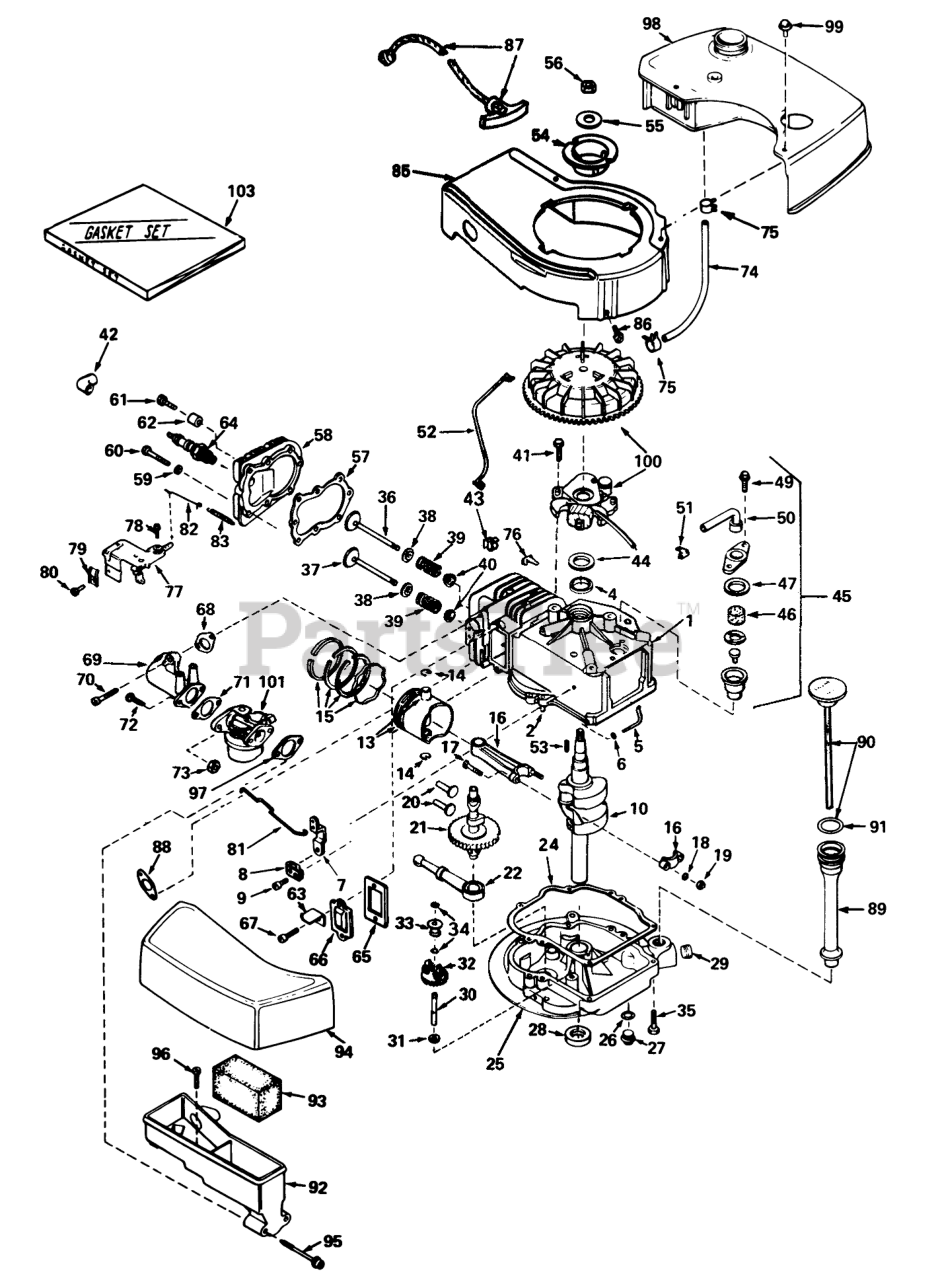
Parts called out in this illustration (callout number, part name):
1	Cylinder assembly (Incl. Ref. #2, 4 & 87)
2	Pin, Dowel
4	OIL SEAL
5	Rod, Governor (Incl. Ref. #6
6	Washer-Flat
7	Governor Lever
8	Clamp-Lever, Governor
9	Screw, Hex Slotted Washer Hd.
10	Crankshaft
13	Piston & Pin Assembly (Incl. 2 of No. 14)(Std.)
13	Piston & Pin Assembly (Incl. 2 of No. 14)(.010 Oversize)
13	Piston & Pin Assembly (Incl. 2 of No. 14)(.020 Oversize)
14	Ring-Retaining, Piston Pin
15	Ring Set Piston (Std.)
15	Ring Set Piston (.010 Oversize)
15	Ring Set Piston (.020 Oversize)
16	Rod Assembly, Connecting (Incl. Ref. #17, 18 & 19)
17	Bolt, Connecting
19	LOCKNUT
20	Lifter-Valve
21	Camshaft(Mech.Comp. Release)
22	Oil Pump ASM
24	Gasket, Mounting
25	Flange Assembly, Mounting (Incl. Ref. #27, 28, 29 & 30)
26	Gasket-Oil Drain
27	Plug Oil Drain
28	Seal Oil
29	Plug Oil Drain
30	Shaft-Governor
31	Washer-Flat
32	Gear Assy., Gov. (Incl. Ref. #31)
33	Spool-Governor
34	Ring-Retaining
35	Screw (1/4-20 x 1-1/4)
36	Valve, Intake (Std.)(Incl. Ref. #38, 39 & 40)
36	Valve, Intake (1/32" Oversize)(Incl. Ref. #38, 39 & 40)
37	Valve, Exhaust (Std.)(Incl. Ref. #38, 39 & 40)
37	Valve, Exhaust (1/32" Oversize)(Incl. Ref. #38, 39 & 40)
38	Cap-Upper Valve Spring
39	Spring-Valve
40	Cap-Valve, Spring
42	Cover-Spark Plug
43	51004 GIL ROTARY TI
44	Gasket, Stator
45	Breather Assembly (Incl. Ref. #46, 47, 49, 50 & 51)
46	Element-Breather
47	Gasket-Breather
49	Screw, Hex Hd. w/Conical
50	Tube, Breaker
51	Clip, Breather
52	Wire, Ground
53	Key-Flywheel
54	Pulley Starter
55	Washer-Spring
56	Hex Nut
57	63573 GIL 42 SNWTHW
58	Head Cylinder
59	Washer
60	Screw
61	Screw Hex Hd. Cap
63	Retainer Clip
64	Plug, Spark (Champion RCJ-8)
65	Gasket-Breather
66	Cover-Valve
68	Gasket, Intake
69	Pipe, Intake
70	Screw (1/4-20 x 1)
71	Gasket-Carburetor
72	Screw
73	Nut and Lock Washer (1/4-28)
74	Line-Fuel
75	Clamp-Line, Fuel
76	Clip, Fuel Line
77	Control Assembly, Speed
78	Screw (10-24 x 3/4)
79	Conduit
80	Screw (10-32 x 3/8)
81	Link Governor
82	Link Governor Spring
83	Spring Governor
85	53024/VAR.GT O/P W/
86	Screw
87	Rope Assy., Starter
88	Gasket Exhaust
89	Tube Fill
90	Dipstick, Oil (Incl. Ref. #91)
92	Body Air Cleaner
93	Filer, Air
94	Cove, Air Cleaner
95	Screw Fil Hd.
96	Screw, Hex Hd.
97	Gasket-Air Cleaner
98	Tank Fuel
99	Screw (10-32 x 35/64)
101	Carburetor (Incl. Ref. #71)
103	53024/VAR.16HP O/P
